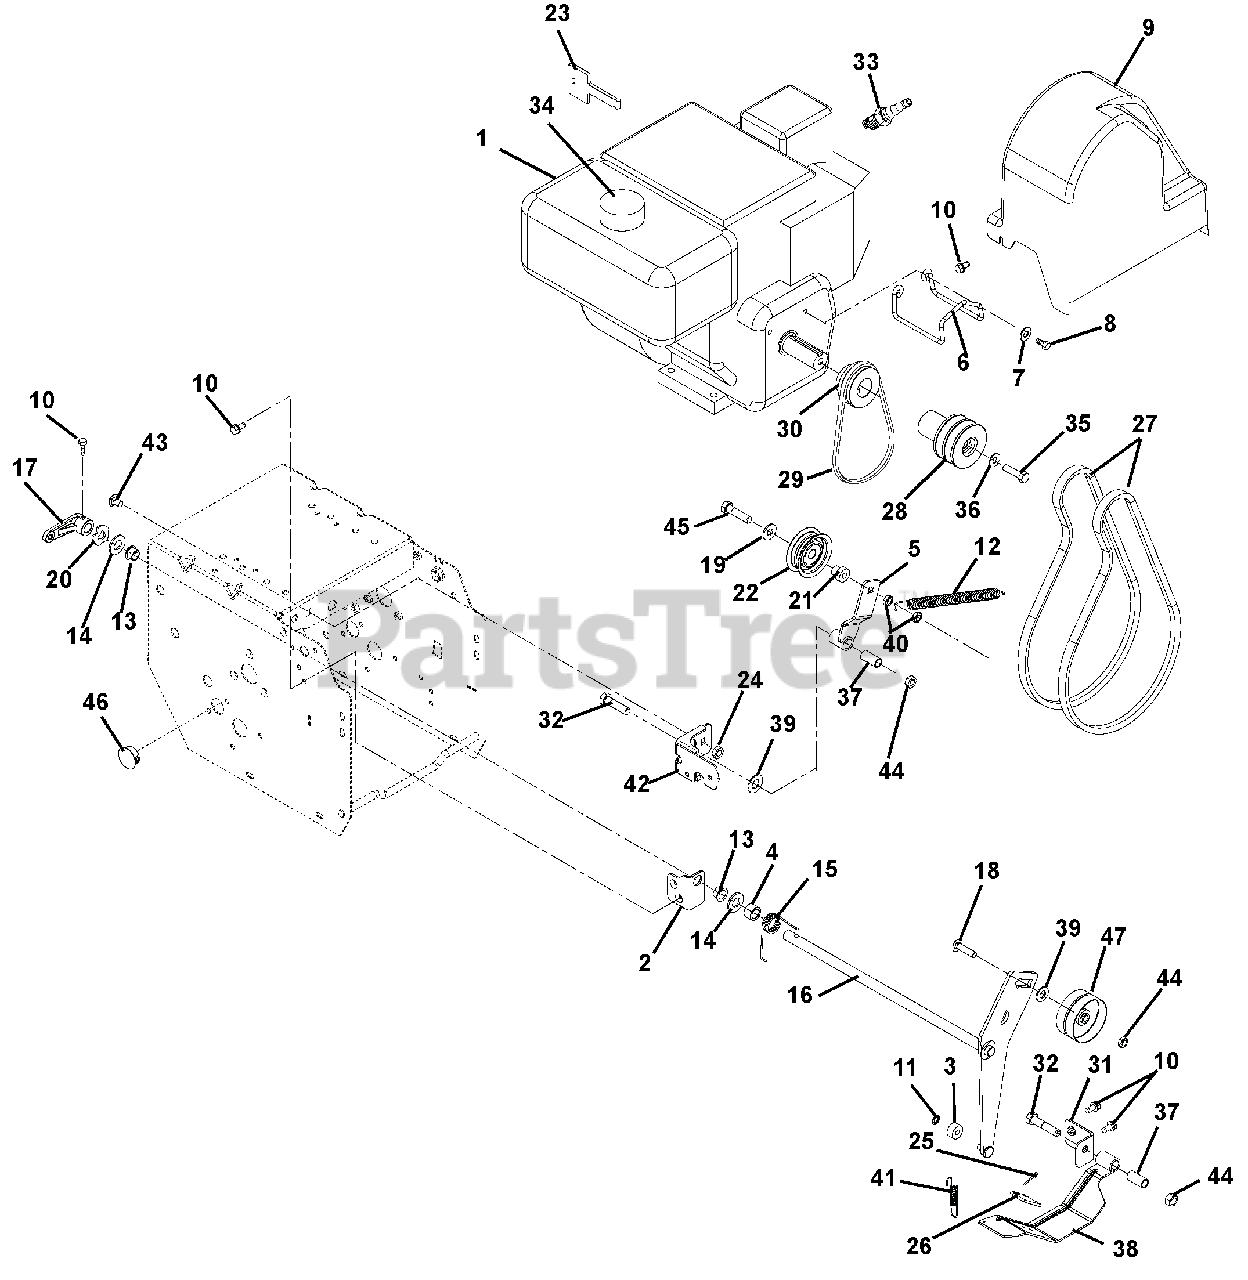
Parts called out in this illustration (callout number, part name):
1	ENGINE, 9.0HP TEC LH318SA 120V
1	ENGINE,11.0HP TEC LH358SA 120V
1	ENGINE, TEC OH318SA 8.0HP 220V
1	ENGINE, 8HP TEC OHV 220V
1	ENGINE, 10HP TECH OHV 220V 18W
2	BRACKET, MOUNT - IDLER ARM
3	BSHG,SLV .270 X .750 X .250
4	BSHG-SLV .510X.751X.475
5	WELDMENT, TRACTION IDLER ARM
6	FINGER, BELT
7	WSHR-LK .312X.097 HVY YWZC
8	BLT-HEX .31-24X.75 YWZC GR5
9	PLZ SEE SERVICE LETTER #L-2166
10	SCR-TAP .25-20X.50 HWH TR YWZ
11	RG-RTNG-EXT .250X.010
12	SG-TENS .062X.56X8.0 WLD 11
13	BUSHING, POLYLINER-.50 SPLIT
14	WSHR-FL-STL.531X1.00X.063 YWZC
15	SG-TORS .075 X .955
16	WELDMENT, ATTACHMENT IDLER ARM
17	ARM, CLUTCH - ATTACHMENT
18	@BLT-RHDSSQNK .38-16X1.75 G5YZ
19	@WSHR-FL-STL.38X.875X.083 YWZC
20	WSHR-WAVE .50X.75X.015 .13FRHT
21	SPCR, BRG .315X.50X.688X.281
22	IDLER
23	KEY, PUSH/PULL - TECUMSEH
24	@NUT-LK-TOP-FLG .31-18 YWZC
25	RVT-POP .187 YZ
26	PAD, BRAKE
27	V-BELT, HA-RAW EDGE (SET)
28	SHEAVE, ATTACHMENT 2-GRV
29	V-BELT, 3L-WRAPPED
30	SHEAVE, DRIVE
31	BRACKET, BRAKE MOUNT
32	@BLT-HEX .38-16X1.75 GR5 YWZC
33	PLUG, SPARK
34	CAP, FUEL - TECUMSEH
35	BLT-HEX .38-24X2.25 YWZC GR5
36	@WSHR-LK .38X.094 REG YWZC
37	BSHG-SLV .385X.500X1.045
38	BRAKE ARM W/PAD
39	@WSHR-FL-STL.406X.812X.065 YWZ
40	@NUT-LK-CTR-JAM .31-18 YWZC
41	SPRING-EXT .047 X .438 X 1.85
42	WELDMENT, FRAME BRACKET
43	@BLT-RHDSSQNK .31-18X.62 G5YZ
44	@NUT-LK-TOP-FLG .38-16 YWZC
45	@BLT-HEX .31-18X1.50 GR5 YWZC
46	PLUG, HOLE - .875" NYLON
47	IDLER-FLAT 2.75X.38 PAINTED
